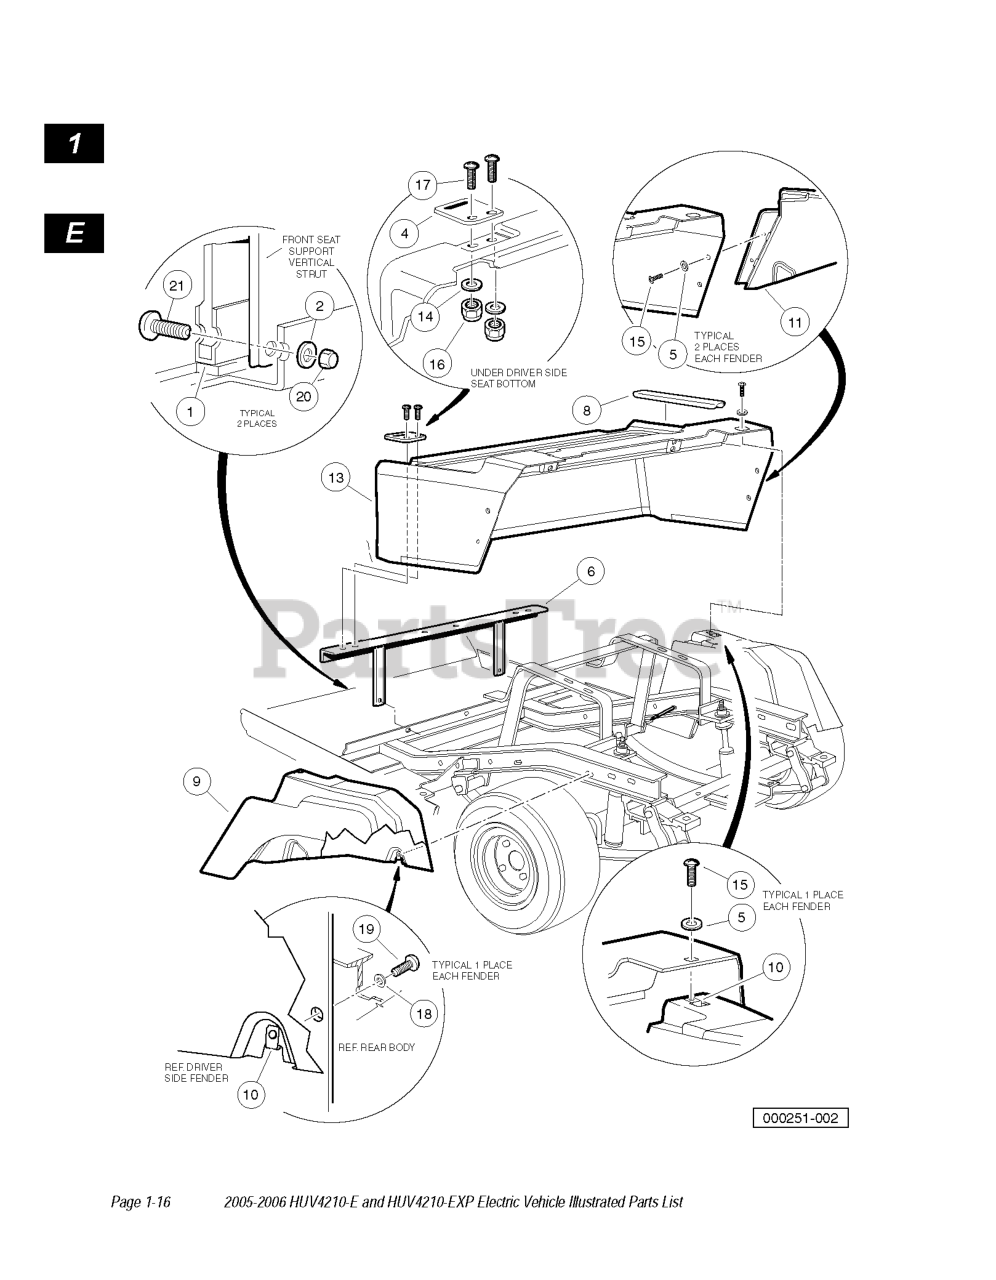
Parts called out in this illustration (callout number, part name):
1	BODY KICK PLATE
4	BODY, HINGE PLATE
6	BODY SUPPORT FRONT
9	FENDER ASM, BODY, DVR
10	U-NUT, 1/4-20 PALNUT BRAND
11	FENDER ASM, BODY, PASS
12	U-NUT, 1/4-20 PALNUT BRAND
13	BODY, REAR, ELECT, CUT, ORG
14	WASHER 1/4 FLAT
15	SCREW, 1/4-20 X .75 HEX
16	LOCKNUT, 1/4-20 NYLON INSERT
17	SCREW, 1/4-20 X 1.0 TRS HD MCH
18	WASHER 1/4 FLAT
19	SCREW, 1/4-20 X .75 HEX
20	LOCKNUT, 1/4-20 NYLON INSERT
21	SCREW, 1/4-20 X 1.0 TRS HD MCH
